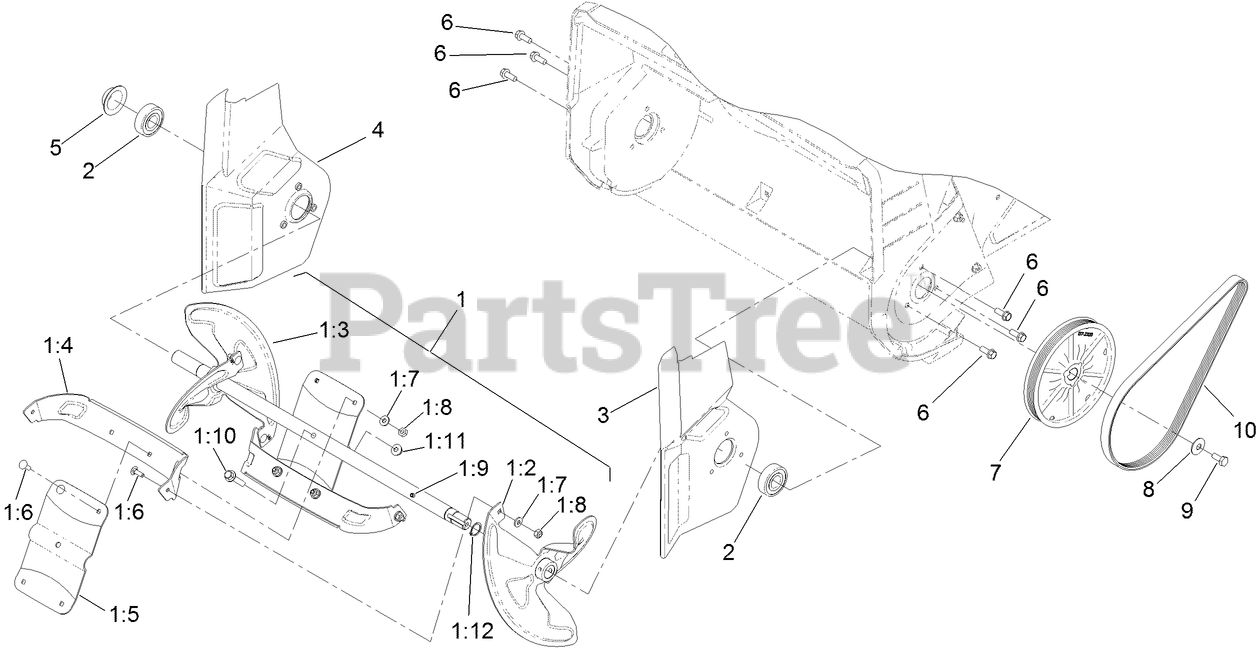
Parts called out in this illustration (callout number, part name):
1	ROTOR ASM
1:2	BLADE-ROTOR, LH
1:3	BLADE-ROTOR, RH
1:4	ROTOR-CENTER
1:5	PADDLE-CENTER
1:6	SCREW-CARR
1:7	WASHER-FLAT
1:8	NUT-LOCK, NI
1:9	PIN-SPIRAL
1:10	SCREW-HHF
1:11	NUT-HF
1:12	RING-SNAP, EXTERNAL
2	BEARING-BALL
3	EXTENSION-LH
4	EXTENSION-RH
5	CAP-SIDEPLATE, RH
6	SCREW-HWH
7	ROTOR PULLEY ASM (6 GROOVE)
8	WASHER-BELLEVILLE
9	SCREW-HH
10	BELT-V, RIBBED
